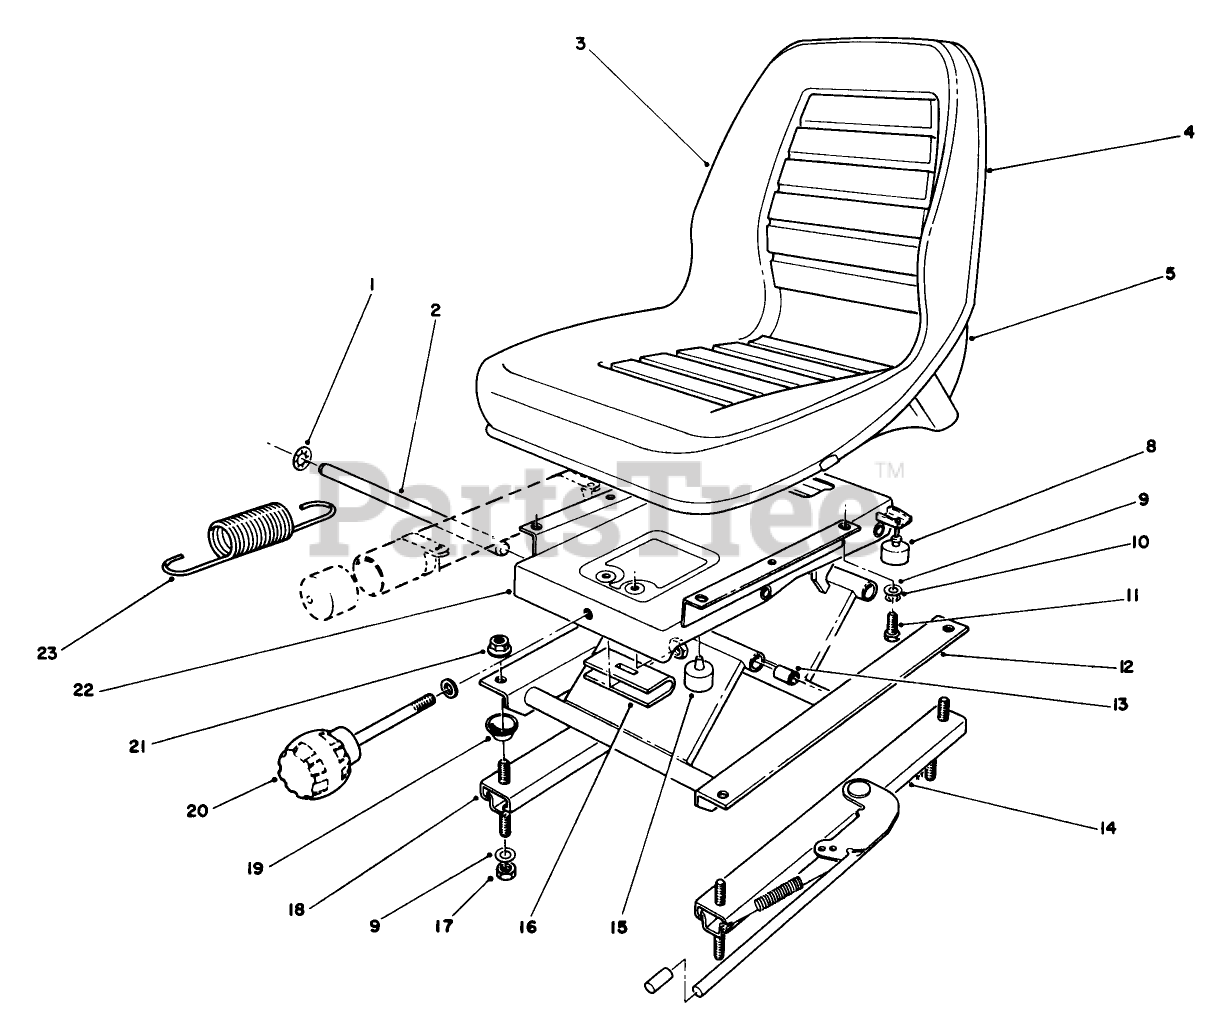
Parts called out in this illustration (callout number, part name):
1	NUT-PUSH
2	SHAFT-PIVOT
3	Cushion-Seat
4	Assembly-Seat (Incl. Ref. #3 & 5)
5	Base
8	BUMPER
9	WASHER-FLAT
10	WASHER-LOCK
11	SCREW-HH
12	FRAME-LOWER
13	SLEEVE-BEARING
14	ADJUSTER W / HANDLE
15	BUMPER-DOWNSTOP
16	SPRING HANGER
17	NUT-LOCK, NI
18	ADJUSTER
19	SPACER-SUSPENSION
20	KNOB-ADJUSTER, TENSION
21	NUT-HF
22	FRAME-UPPER
23	SPRING-EXTENSION
